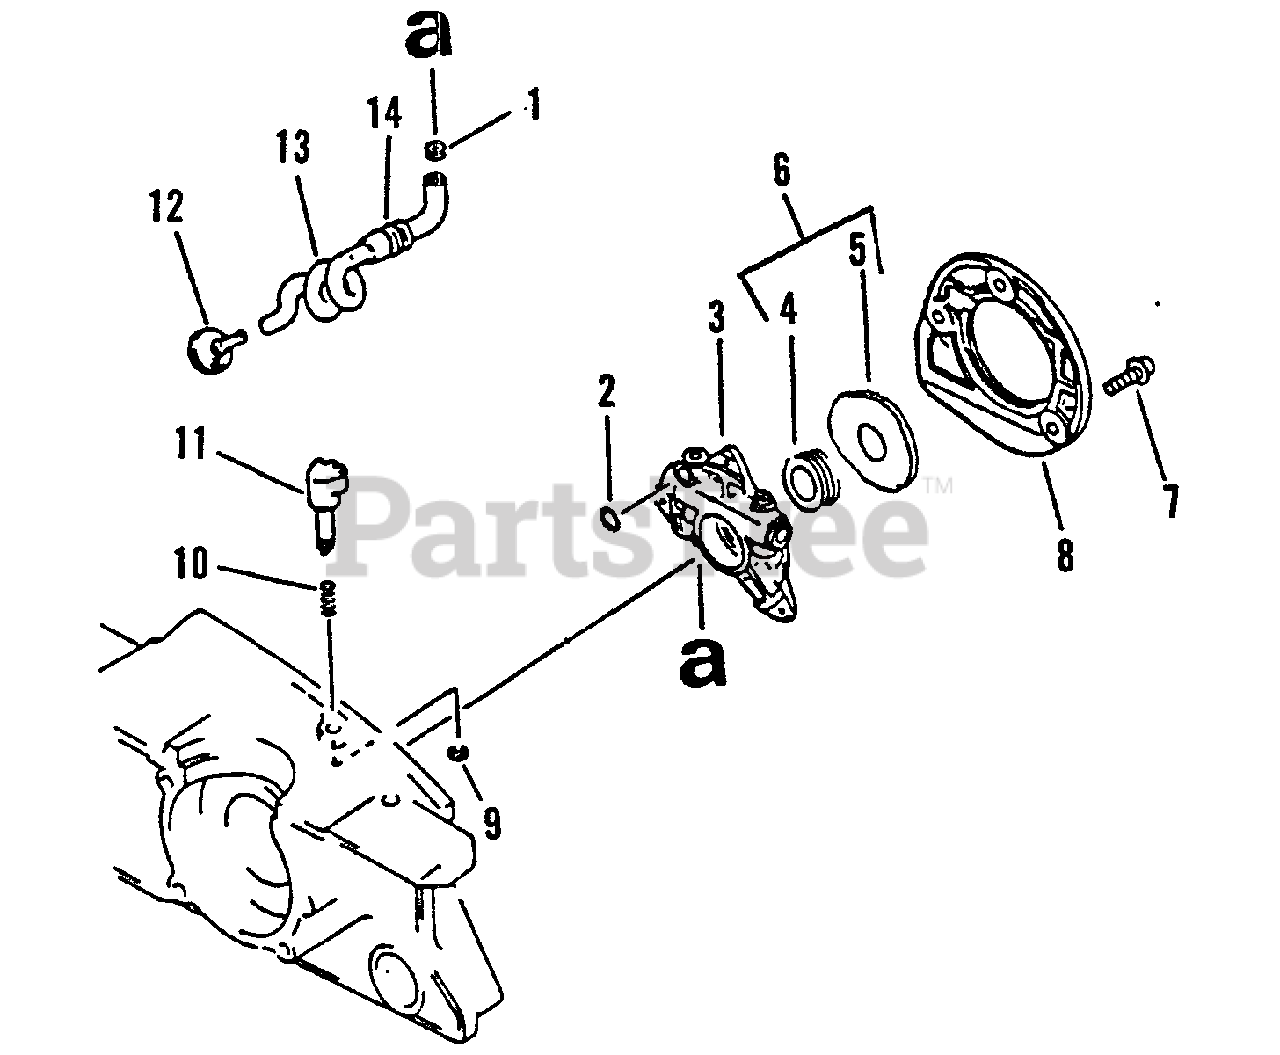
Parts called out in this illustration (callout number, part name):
1	CLIP - 6.5
2	O-RING - 3
3	AUTO-OILER ASSY
4	GEAR - WORM
5	WASHER - 12
6	GEAR - WORM
7	SCREW - 4X14
8	COVER, OIL PUMP
9	RING, RETAINING - 3
11	DIAL, AUTO-OILER
12	FILTER, OIL
13	PIPE, OIL - SPIRAL
